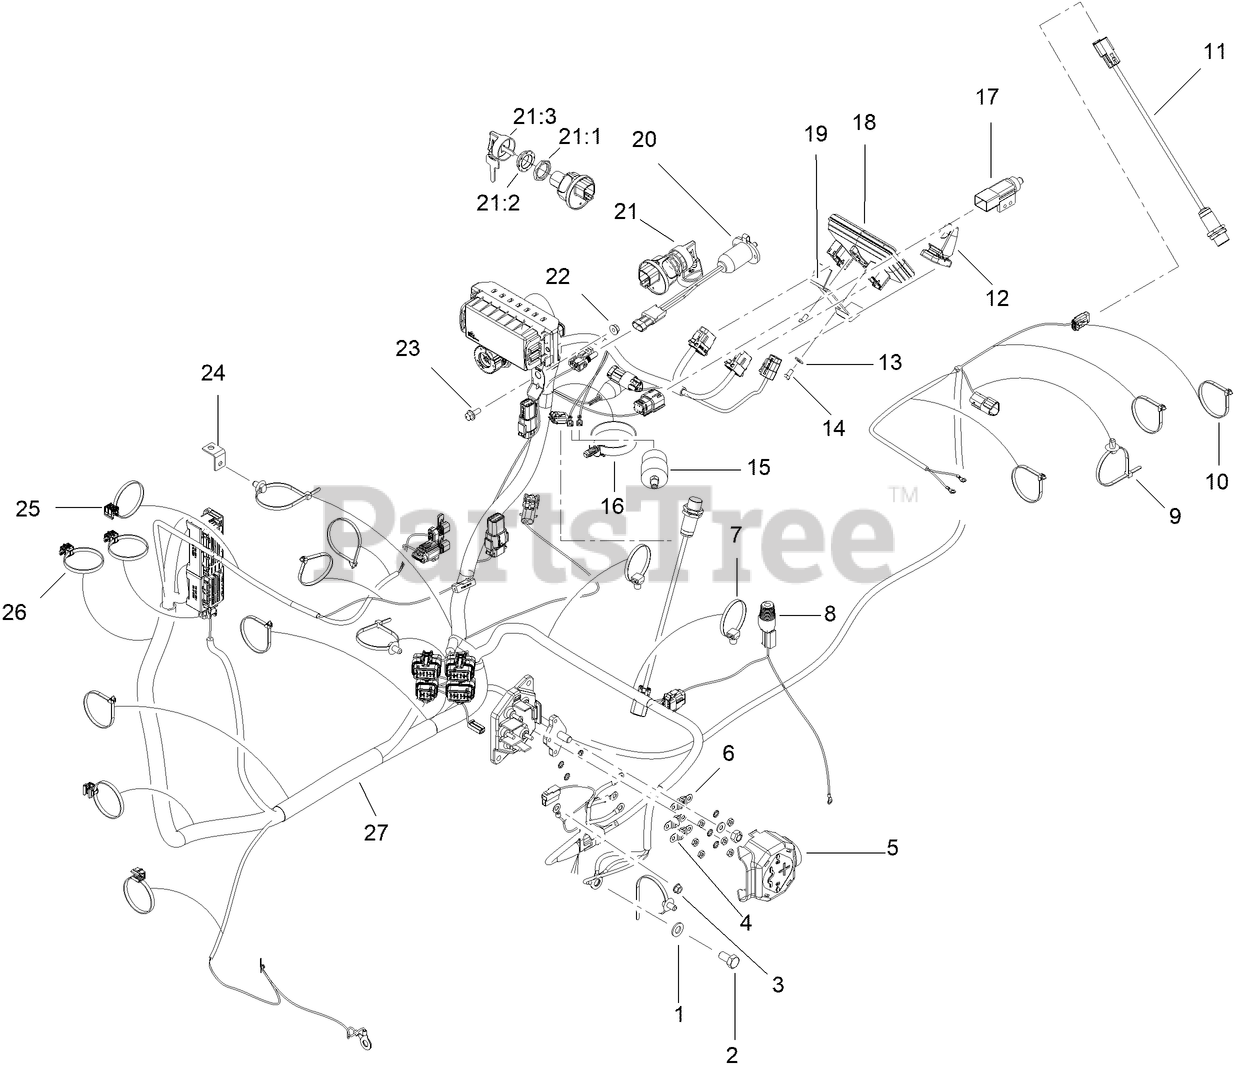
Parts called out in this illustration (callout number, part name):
1	WASHER-FLAT
2	SCREW-HH
3	NUT-HF
4	BK/AMI 60 AMP FUSE
5	MAIN FUSE HOLDER (3 BK/AMI FUSES)
6	BK/AMI 80 AMP FUSE
7	FIR TREE SMALL TIE
8	SWITCH-TEMP, 200 DEGREE
9	FIR TREE CABLE MOUNT
10	CABLE TIE (1/16" TO 4")
11	PROXIMITY SWITCH 18MM NPN N/O
12	HPW SWITCH (FRICTION HOLD)
13	WASHER-PLAIN
14	SCREW-HH
15	SWITCH-PRESSURE, VACUUM
16	HEAVY DUTY FIR TREE (.04-.62 THK)
17	PLUNGER SWITCH
18	CCPILOT VI_2 3.5" DISPLAY
19	DISPLAY BRACKET
20	ACCESSORY SOCKET
21	IGNITION SWITCH ASM
21:1	NUT-HEX
21:2	NUT-FACE, M22 (PLASTIC)
21:3	SET-KEY, IGNITION
22	NUT-HF
23	SCREW-HHF
24	BRACKET
25	EDGE CLIP SIDE VERTICAL (.12-.24)
26	EDGE CLIP SIDE HORIZONTAL (.12-.24)
27	FRAME HARNESS
